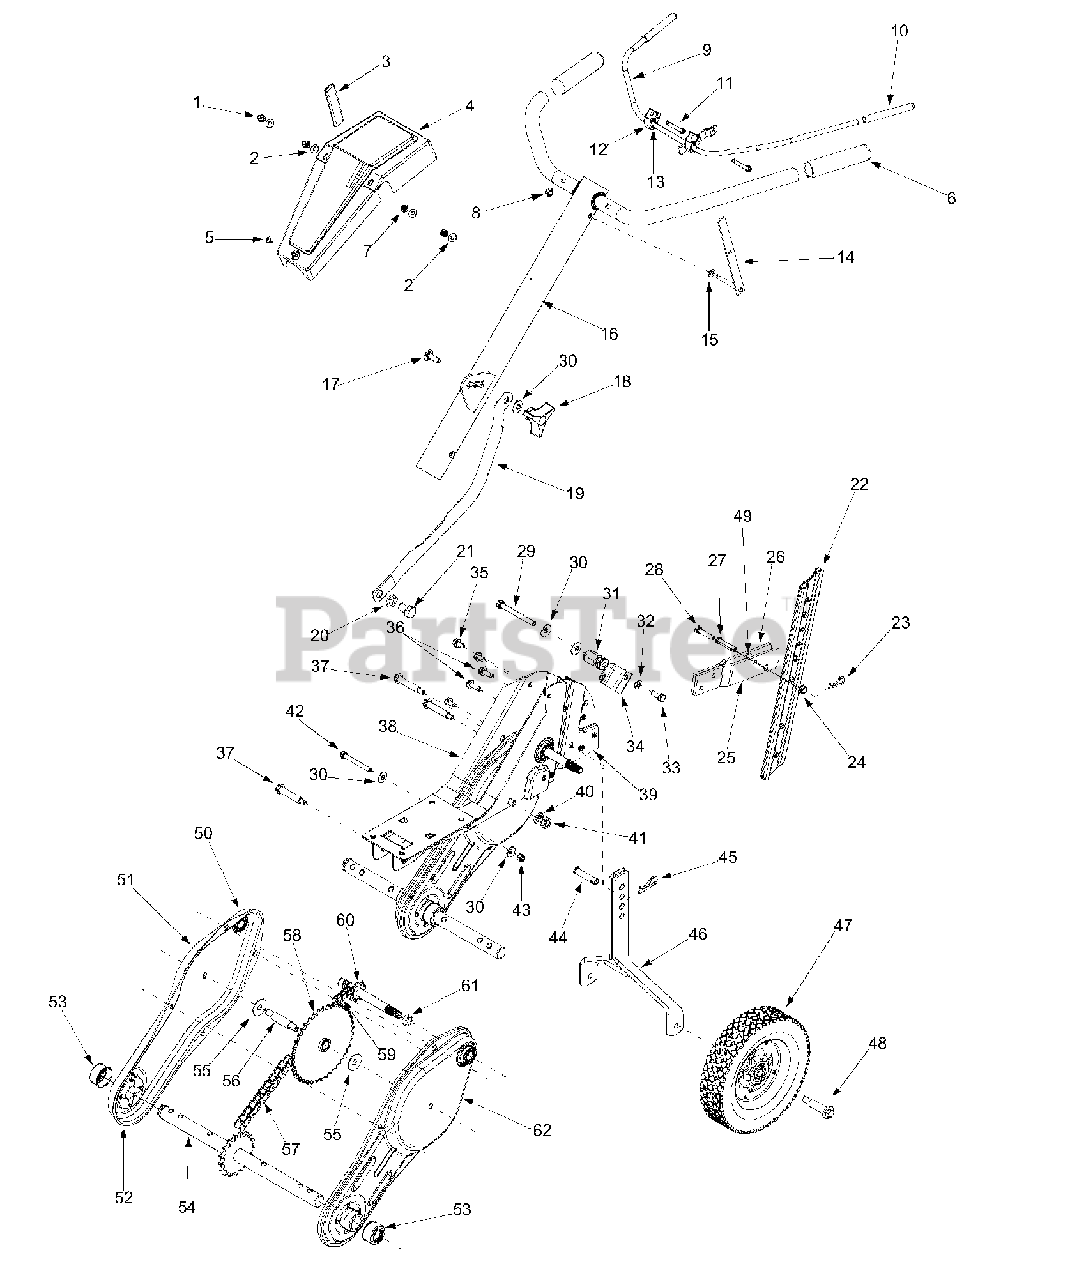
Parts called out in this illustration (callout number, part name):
1	Acorn Lock Nut 1/4-20
2	Flat Washer .271" I.D. x .630" O.D.
3	Reverse Handle Grip
4	Handle Cover
5	Truss Mach. Scr. #10 x 1/2" Lg.
6	Grip-Handle
7	Hex Nut 1/4-20 Gr.2
8	Cap Speed Nut
10	Grip-Clutch
11	Hex Bolt 1/4-20 x 2.25" Lg. Gr.5
12	Clutch Handle Holder
13	Flat Washer .385" I.D. x .62" O.D.
15	Flat Washer .344" I.D. x .62" O.D.
18	Hand Knob
20	Lock Washer 1/2
21	Hex Bolt 1/2-20 Gr. 5
23	Cotter Pin
24	Hex Flange L-Nut 5/16-18
27	Clevis Pin
28	Hex Bolt 5/16-18 x 1.5" Lg.
29	Hex Bolt 5/16-18 x 3" Lg.
30	Wash. Bell. .340" I.D. x .872" O.D.
31	Spec. Hex Nut
32	L-Wash. 5/16" I.D.
33	Hex Bolt 5/16-18 Gr. 5
35	Hex Wash Screw 5/16-18 x .62"
36	Hex Wash. Hd. TT-Tap Scr.
37	Shdl. Bolt 5/16-18
40	Lock Washer 7/16
41	Jam Nut 7/16-20 Gr. 2
42	Hex Bolt 5/16-18 x 2.75" Lg.
43	Hex Nut 5/16-18 Thd.
44	Clevis Pin
45	Cotter Pin
47	Wheel Ass'y 8" x 1.75"
48	Shoulder Screw .496 x 1.445
49	Spacer
50	Chain Case Assembly Complete
51	Chain Case RH
52	Gasket
53	Shaft Seal 1.0
54	Shaft Assembly
55	Flat Washer .442 ID x 1.38 OD
56	Jack Shaft
57	Chain #50 x 46 Links
58	Sprocket Assembly
59	Chain #420 x 46 Links
60	Input Shaft Assembly
61	Input Shaft Spacer
62	Chain Case LH
